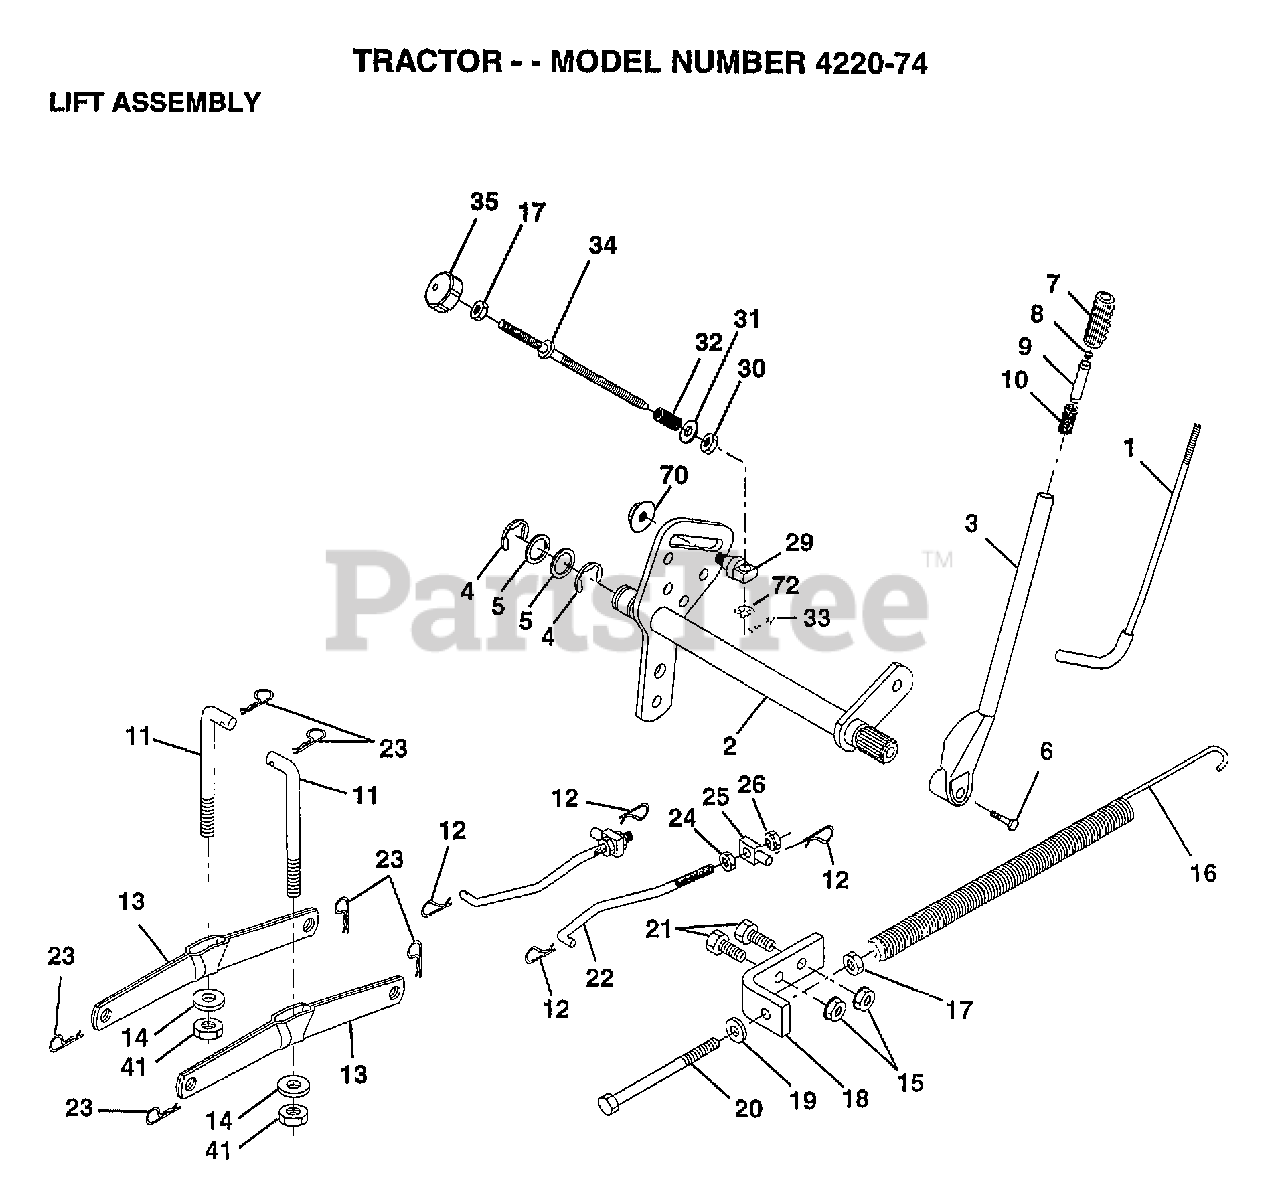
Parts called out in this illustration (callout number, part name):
1	LEVER ROD LT
2	SHAFT AMS LIFT
4	E-RING
5	WASHER
6	"BOLT,HEX"
7	GRIP
10	SPRING T
11	LINK.LIFT.MWR.VGT
12	RETAINER.SPRING
13	ARM SUSP REAR
14	BEARING PVT LH
17	NUT
18	BRACKET SPRING AS
19	WASHER
20	BOLT-ADJ SPRING T
21	BOLT
22	LINK.FRONT
24	NUT
25	TRUNION
26	NUT.LK.W/WSH.1/2.
29	TRUNNION
30	NUT T
31	WASHER
32	SPRING.COMP.INF.H
34	ROD.ADJ.LIFT
35	KNOB INF 3/8-16
41	NUT.CROWNLOCK.3/8
70	NUT.HXFLG.LOCK.
72	NUT PUSH M
